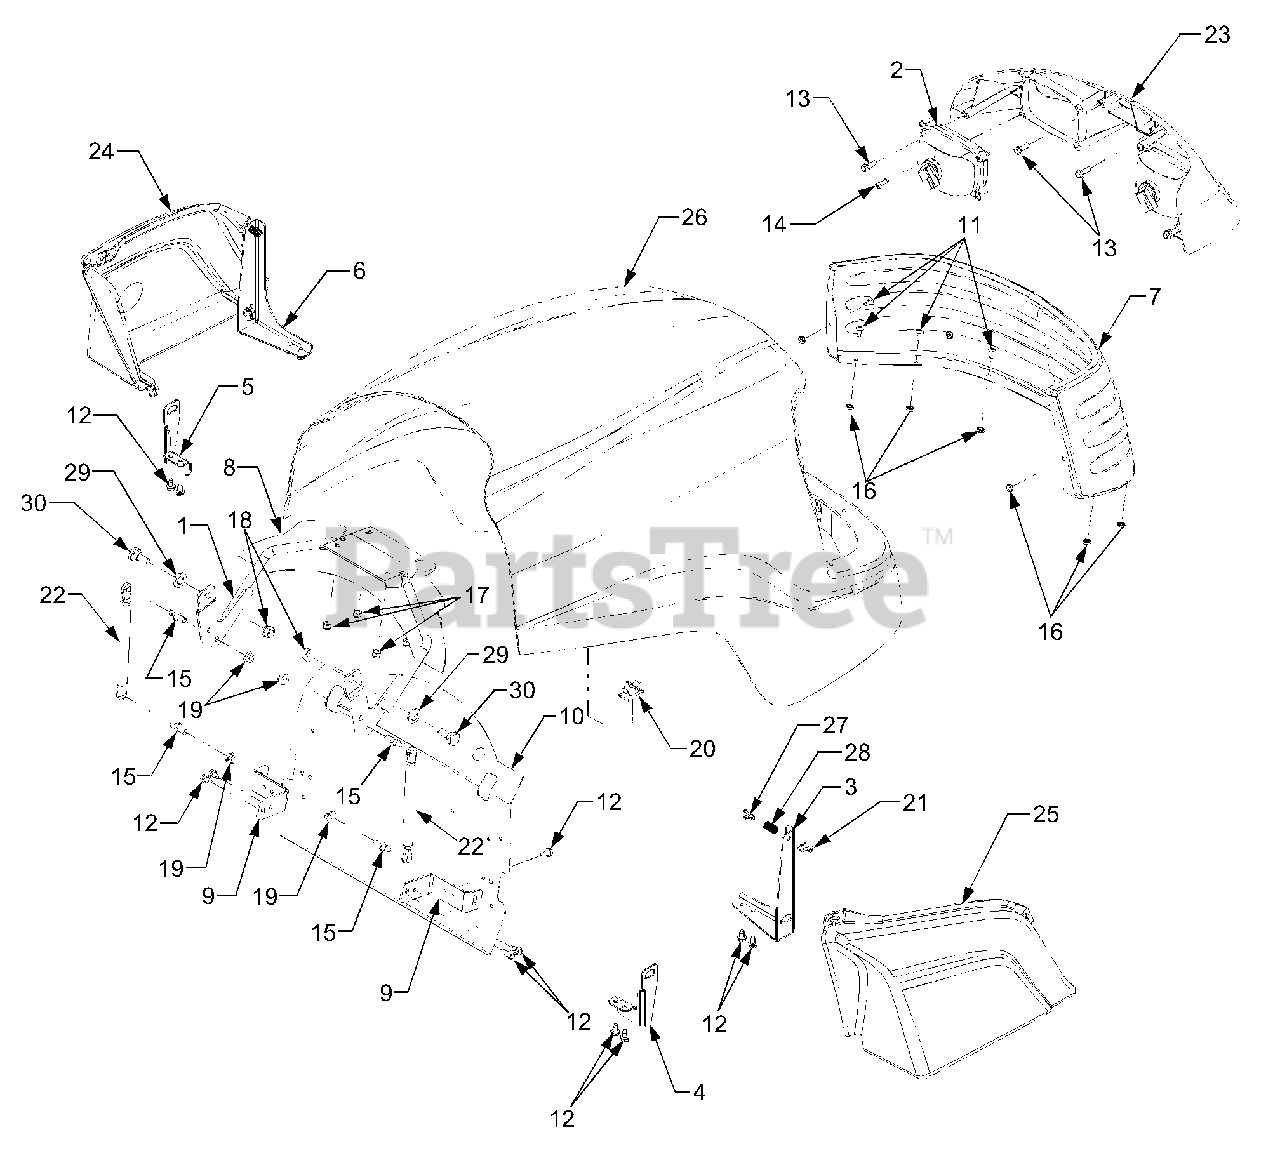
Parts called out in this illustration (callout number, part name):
1	Hinge Assembly, Hood
2	Headlight Assembly
3	Bracket, Side Panel Mtg. RH
4	Bracket, Side Panel Mtg. RH Rear
5	Bracket, Side Panel Mtg. LH Rear
6	Bracket, Side Panel Mtg. LH
10	Shield, Lower Heat
11	Screw, Truss Hd, 10-24 x .5
12	Screw, Hex Wash Hd Tapp 1/4-20 x .5
13	Screw, Hex Wash. Hd 1/4-20 x .75
14	Screw, Truss Phil. Hd. 12-16 x .75
15	Stud, Cylinder, 5/16-18 Thrd
16	Nut, Hex Sems, 10-24
17	Nut, Hex Nylon Insert Lock, 1/4-20
18	Nut, Hex Flange Lock, 3/8-16
19	Nut, Hex Flange Lock, 5/16-18
20	Clip, Retaining
21	Latch, 1/4 Turn Panel
22	Cylinder, Gas Spring
23	Bezel, Headlight
24	Panel, Side LH
25	Panel, Side RH
26	Hood, Service Kit
26	Hood
27	Clip, Spring
28	Spring, Compression
29	Washer, Flat, .531 x .93 x .090
30	Screw, Shoulder, .5 x .27 Lg 3/8-16
